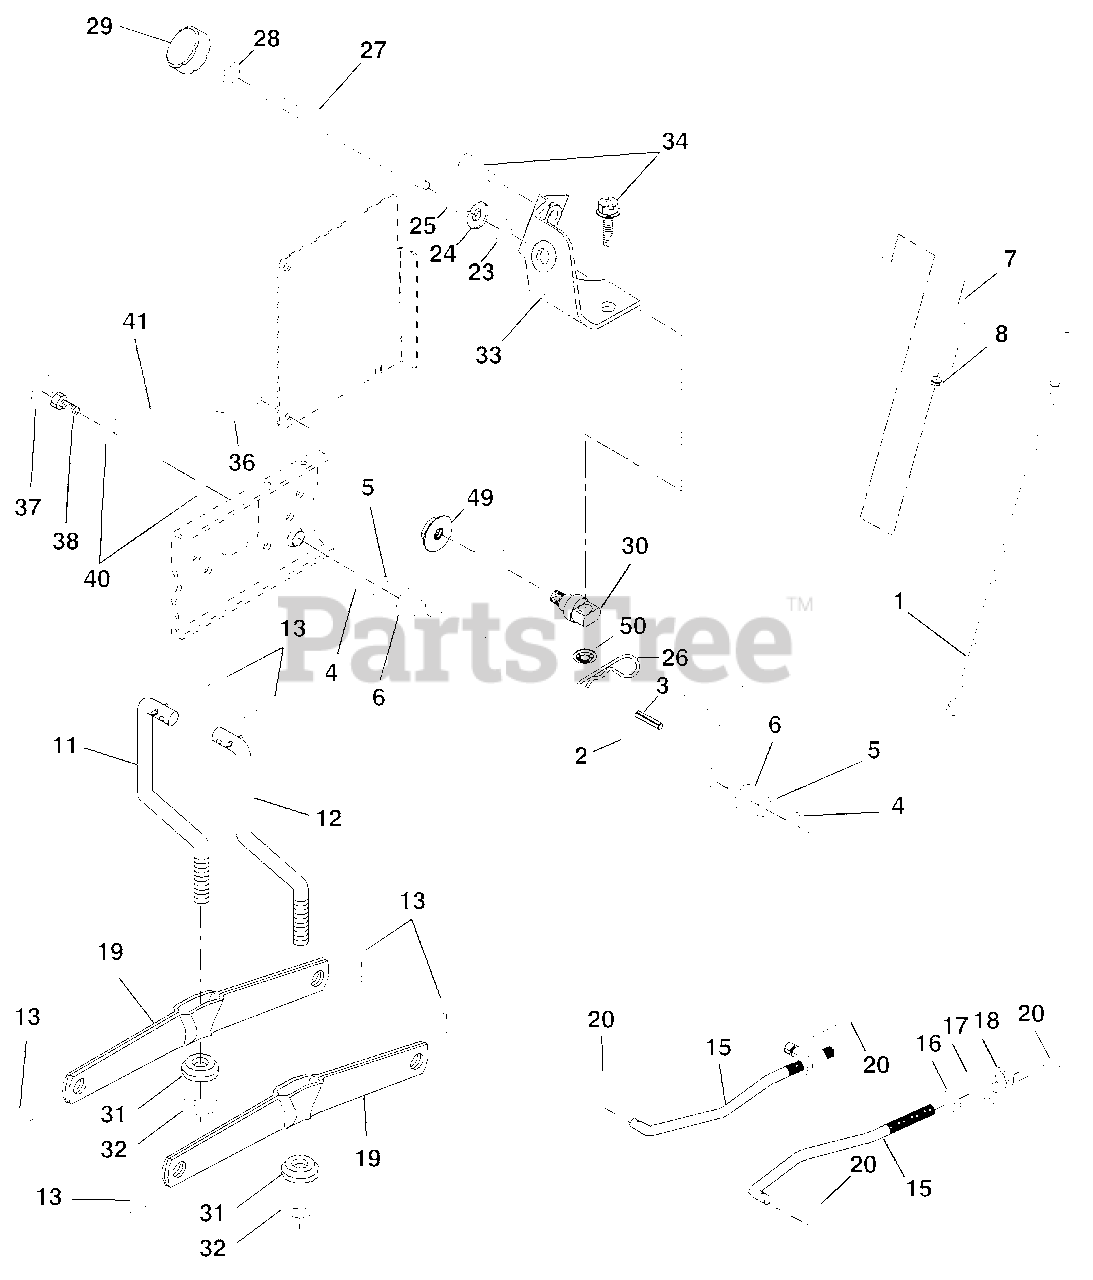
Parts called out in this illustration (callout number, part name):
1	Wire Asm Inner/Sprg W/plunger LT
2	Shaft Asm Lift RH w/Inf
3	Pin Groove 1 500 Zinc
4	E Ring #5133-62
5	Washer 21/32 X 1 X 21 Ga
6	Bearing Nylon Blk 629 Id
7	Grip Handle
8	Button Plunger
11	Link Lift LH Fixed Length
12	Link Lift RH Fixed Length
13	Retainer Spring
15	Link Front
16	Nut Jam Hex 1/2-13 Unc
17	Trunnion Blk Zinc
18	Nut Lock w/Wsh 1/2-13unc
19	Arm Suspension Rear
20	Retainer Spring
23	Nut Special
24	Washer 13/32 X 5/8 X 16 Ga
25	Spring 2-1/8"
26	Retainer Clip
27	Rod Adj Lift Zinc 7.49 Wrk Lg
28	Nut Hex Jam 3/8-16 Unc
29	Knob Inf 3/8-16 Unc Blk W/sym
30	Trunnion Infin Height
31	Bearing Pvt Lift
32	Nut Crownlock 3/8 - 24
33	Bracket Infinite Height
34	Screw Thdrol 3/8-16 x 1/2
36	Pointer Height Indicator
37	Plug Hole Blk 1.485/1.515 Dia.
38	Screw 5/16-18 x 1
40	Washer 11/32 x 1-1/2 10 Ga.
41	Indicator Height STLT
49	Nut Hex Flange Lock
50	Nut PUsh Phos & Oil
